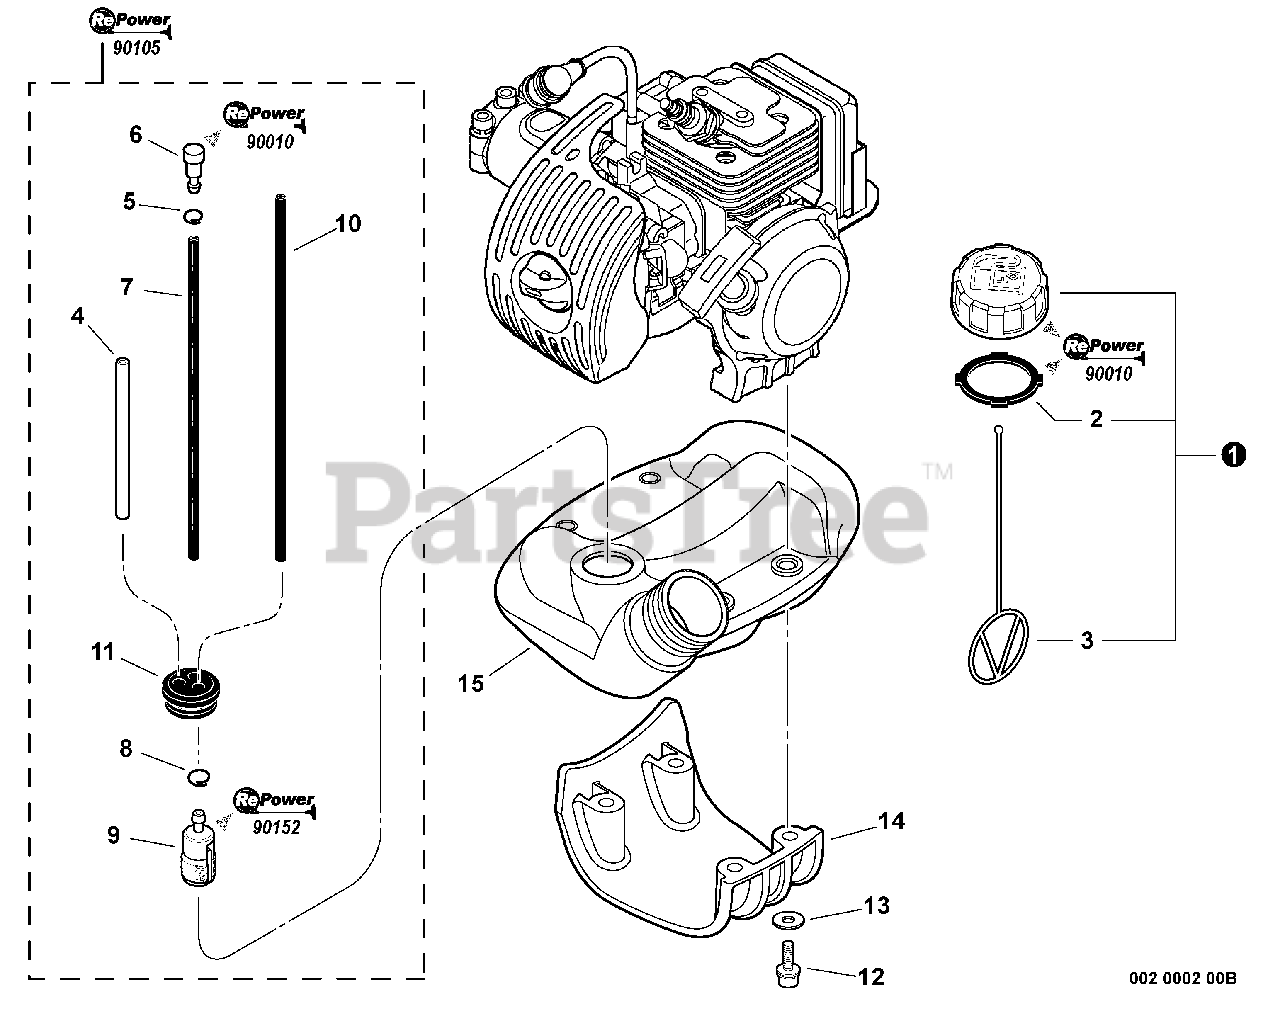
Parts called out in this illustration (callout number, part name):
1	CAP ASSY, FUEL
2	GASKET, FUEL CAP
3	CONNECTOR, CAP L= 100 MM
4	PIPE, FUEL 3×6×75 CLEAR
5	CLIP Ø6.5 MM
6	VENT ASSY
7	PIPE, FUEL 3×6×35 BLACK
8	CLIP 6 MM
9	FILTER, FUEL 125-528
10	PIPE, FUEL 3×5×195 BLACK
11	GROMMET, FUEL
12	BOLT 5×25
13	WASHER 5.5×12×0.8
14	GUARD, FUEL TANK
15	TANK, FUEL
16	FUEL SYSTEM KIT
17	TUNE-UP KIT - REPOWER
18	CAP/VENT KIT - REPOWER
